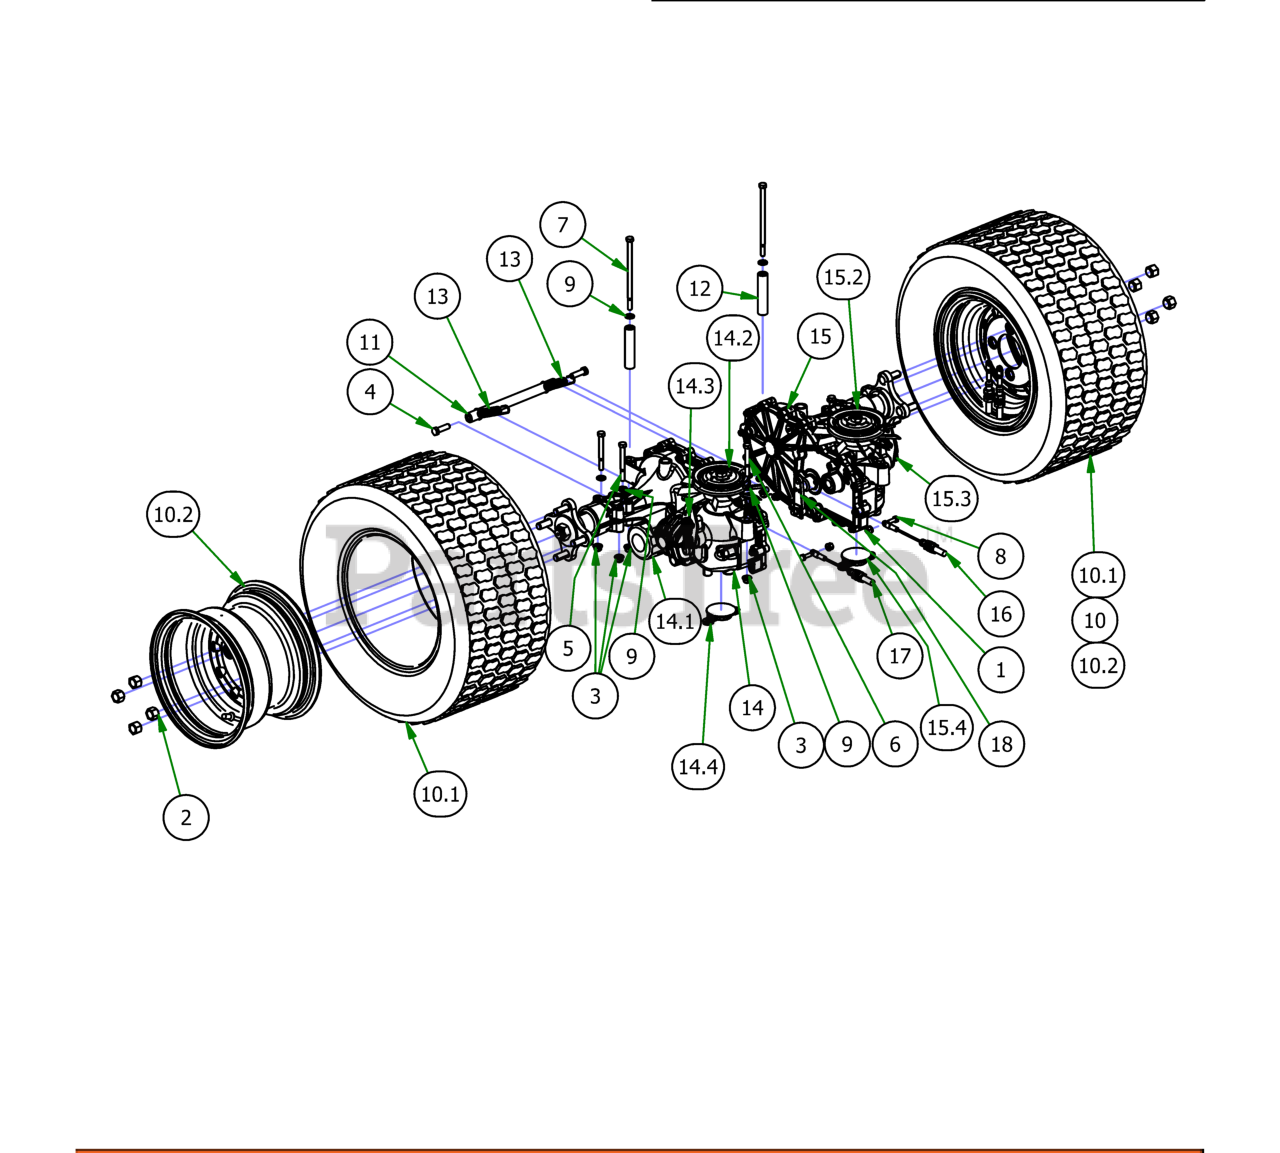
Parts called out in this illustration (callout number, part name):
1	1/4-20 Nylon Insert flange Nut
2	Acorn Lug Nut
3	5/16" Nylon Flange Nut
4	3/8'' x2'' Hex Bolt
5	5/16" x 3" Hex Bolt
6	5/16" x 2 1/2" Bolt
7	5/16" x 6" Bolt
8	1/4" x 3/4" Hex Bolt
9	5/16" Flat Washer
10	ZT Tire and Rim Assembly 22 x 11 - 10
10.1	ZT Tire Only 22x11-10
10.2	ZT Wheel Only 22x11-10
11	2017 Transaxle Spacer-ZT
12	2017 Transaxle Spacer
13	Brake Return Spring
14	2021 RH 2800 Transaxle
14.2	Fan/Pulley Kit for ZT
14.3	Transaxle Spring
14.4	ZT Transaxle Charge Plate/With O'Ring
15	2021 LH 2800 Transaxle
15.2	Fan/Pulley Kit for ZT
15.3	Transaxle Spring
15.4	ZT Transaxle Charge Plate/With O'Ring
16	2021 Load Balanced Brake Cable 1
17	2021 Load Balanced Brake Cable 2
